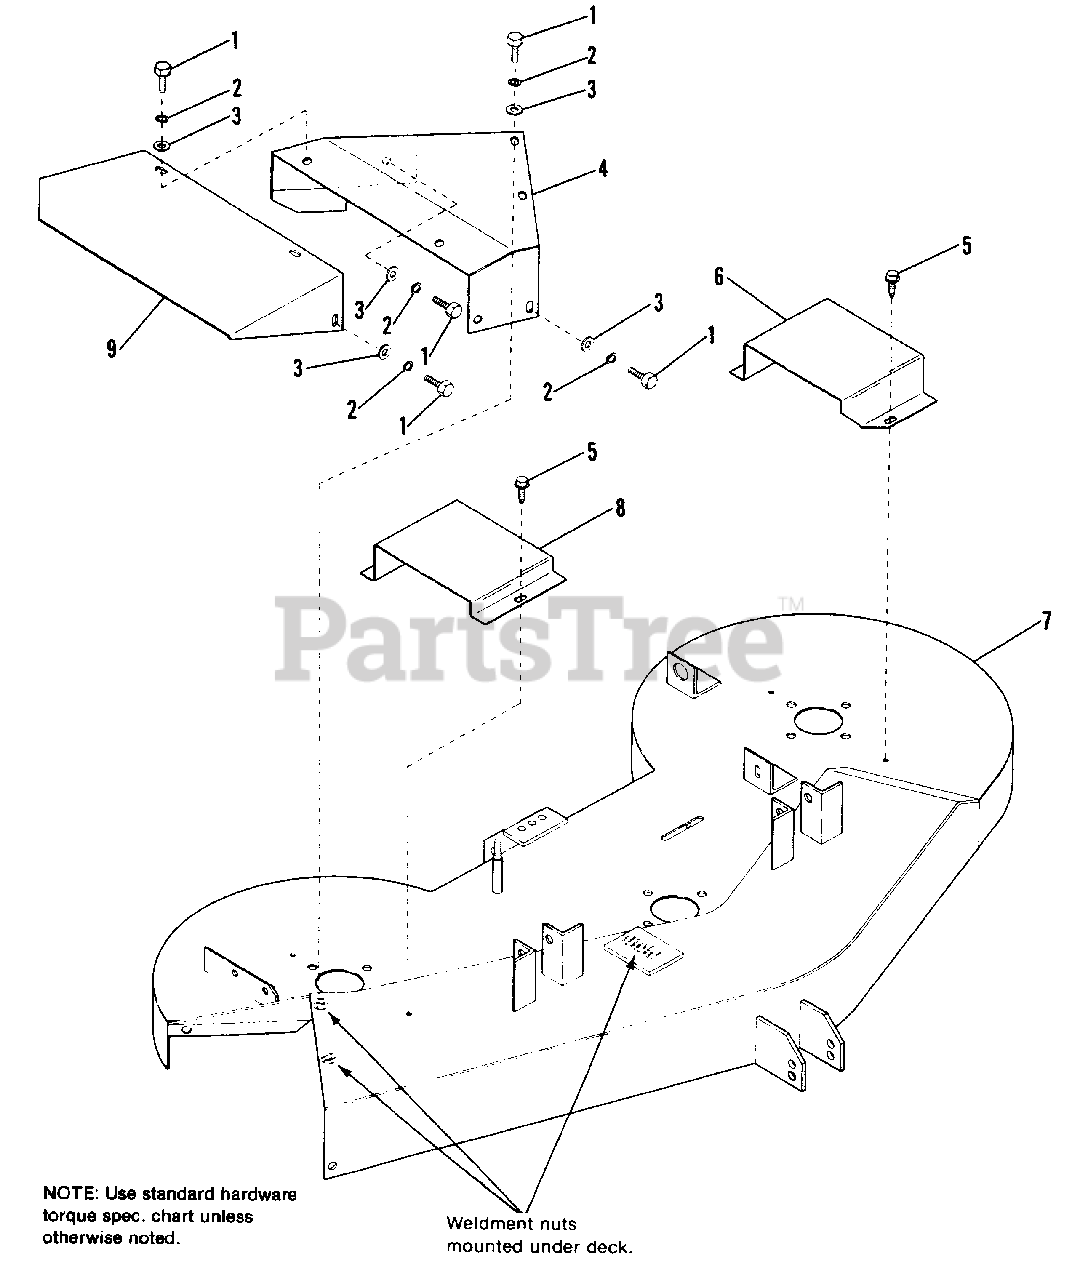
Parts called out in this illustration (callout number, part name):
1	CAPSCREW, Hex, 5/16-18 x 3/4
2	LOCKWASHER, Spring, 5/16
3	WASHER, Plain, 5/16
4	TUNNEL EXTENSION ASSY.
5	SCREW, Taptite, 5/16-18 x 1/2 (Qty. 2 used on 46" Mower)
6	GUARD, L.H.
7	HOUSING ASSY., 46"
7	HOUSING ASSY., 54"
7	HOUSING ASSY., 60"
7	HOUSING ASSY., 66"
8	GUARD, R.H. (54", 60", 66" Mowers)
9	DEFLECTOR ASSY.
